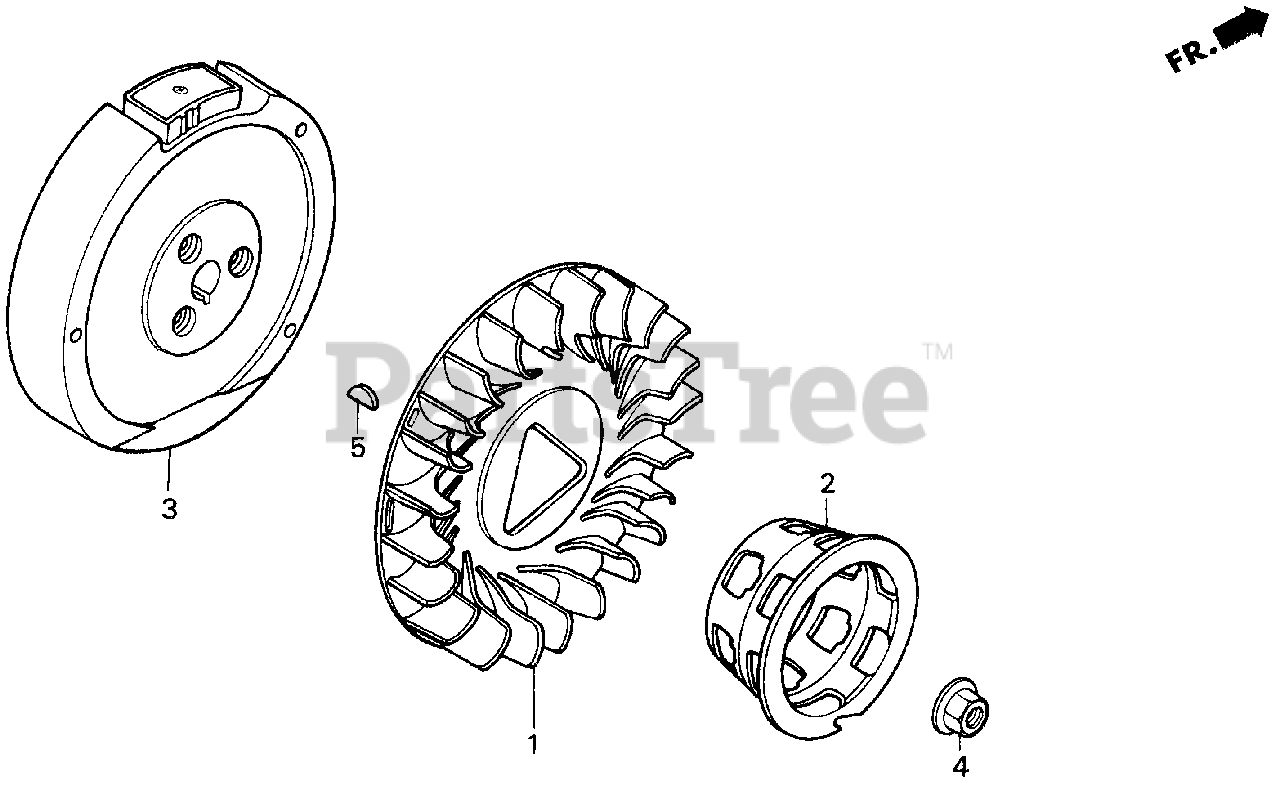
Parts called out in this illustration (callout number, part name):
1	FAN, COOLING
2	PULLEY, STARTER
3	FLYWHEEL (LAMP)
4	NUT, SPECIAL (16MM)
4	NUT, SPECIAL (16MM) (1)
5	KEY, SPECIAL WOODRUFF (25X18)
